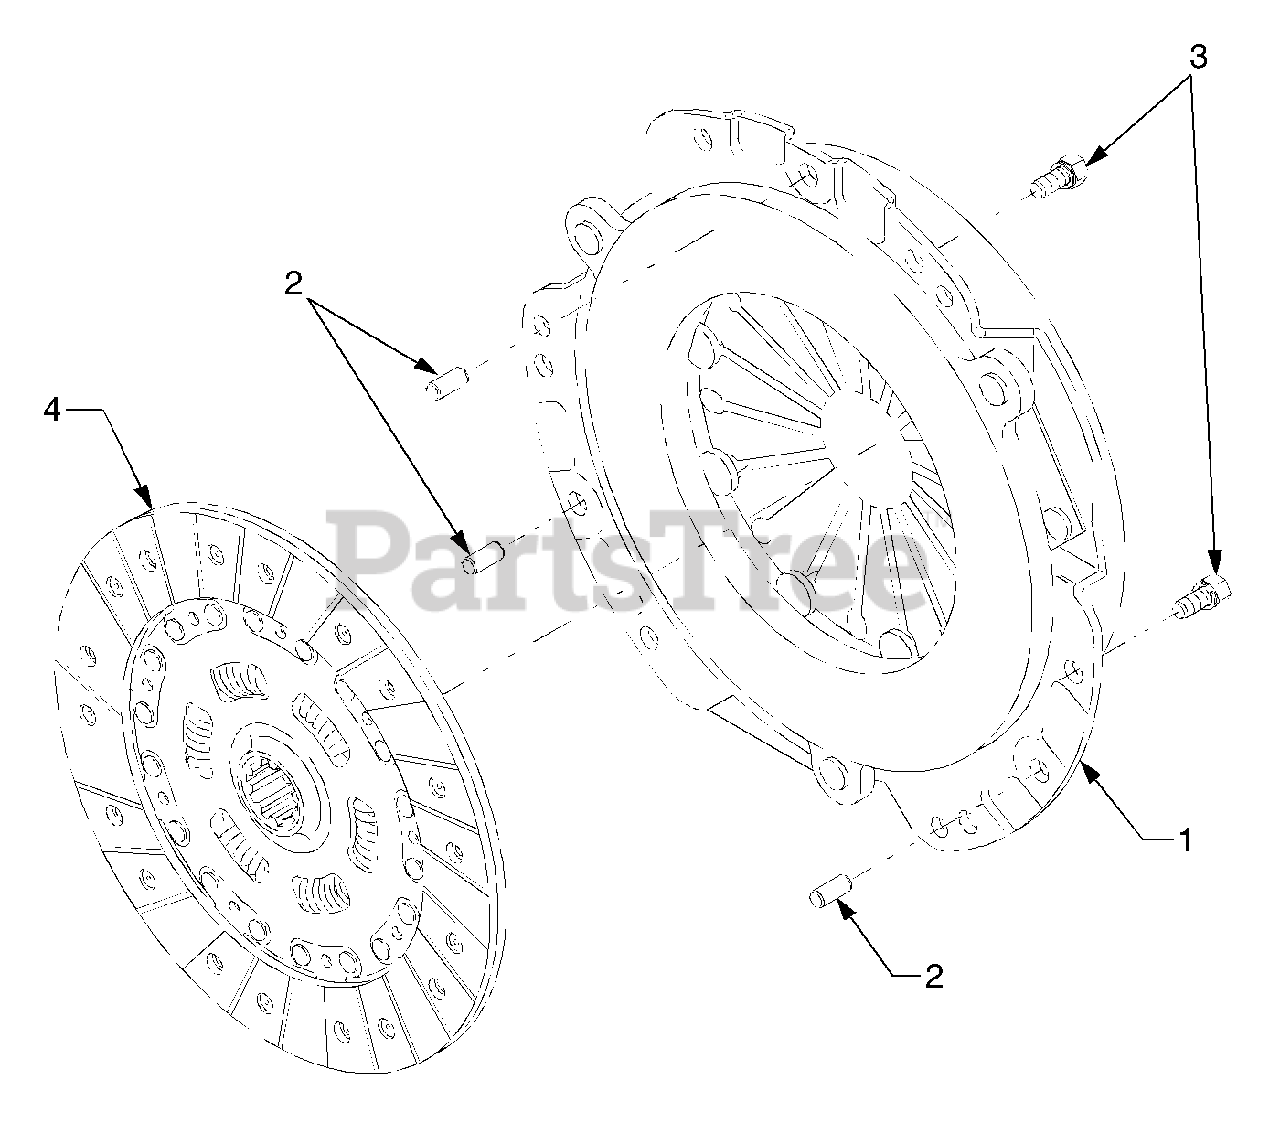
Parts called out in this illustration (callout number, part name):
1	Clutch Cover Ass'y
2	Pin, Straight
4	Clutch Disc Ass'y
